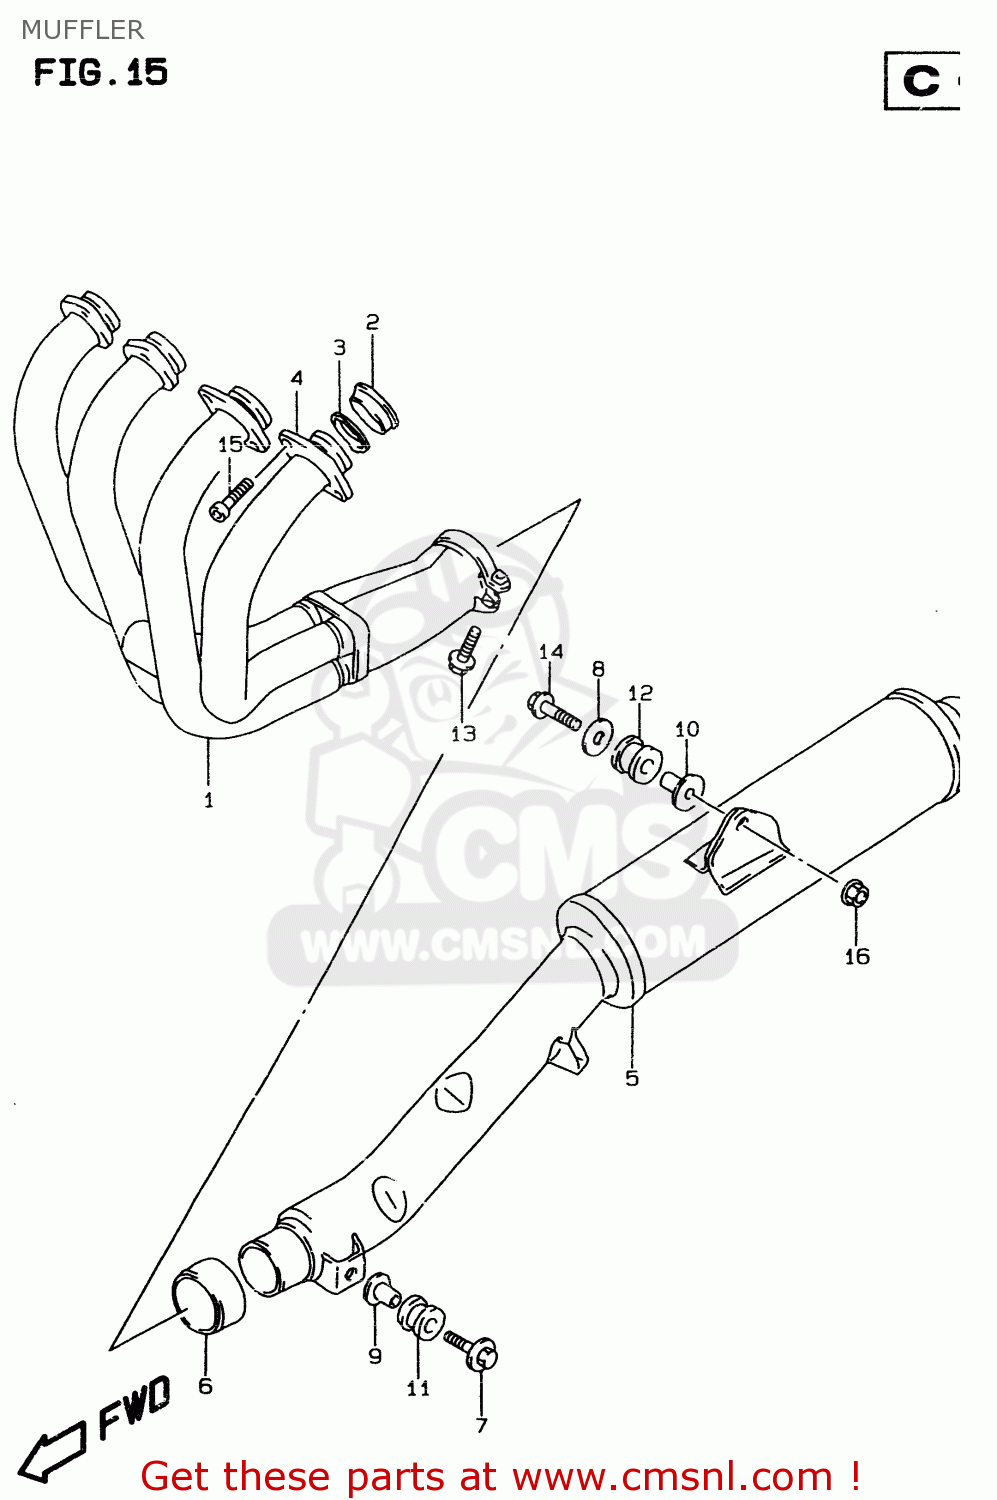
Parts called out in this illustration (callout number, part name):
1	EXHAUST
2	PLATE,EXHAUST PIPE
3	GASKET,EXHAUST (NAS)
4	CLAMP,EXHAUST PIPE
5	BODY,MUFFLER
6	CONNECTOR,MUFFLER
7	BOLT 8X40
8	WASHER (8.1X33X1.6)
9	SPACER(8.6X12X24.2)
10	SPACER(8.6X12X27.1)
11	CUSHION
12	CUSHION
13	BOLT
14	BOLT
15	BOLT
16	NUT
